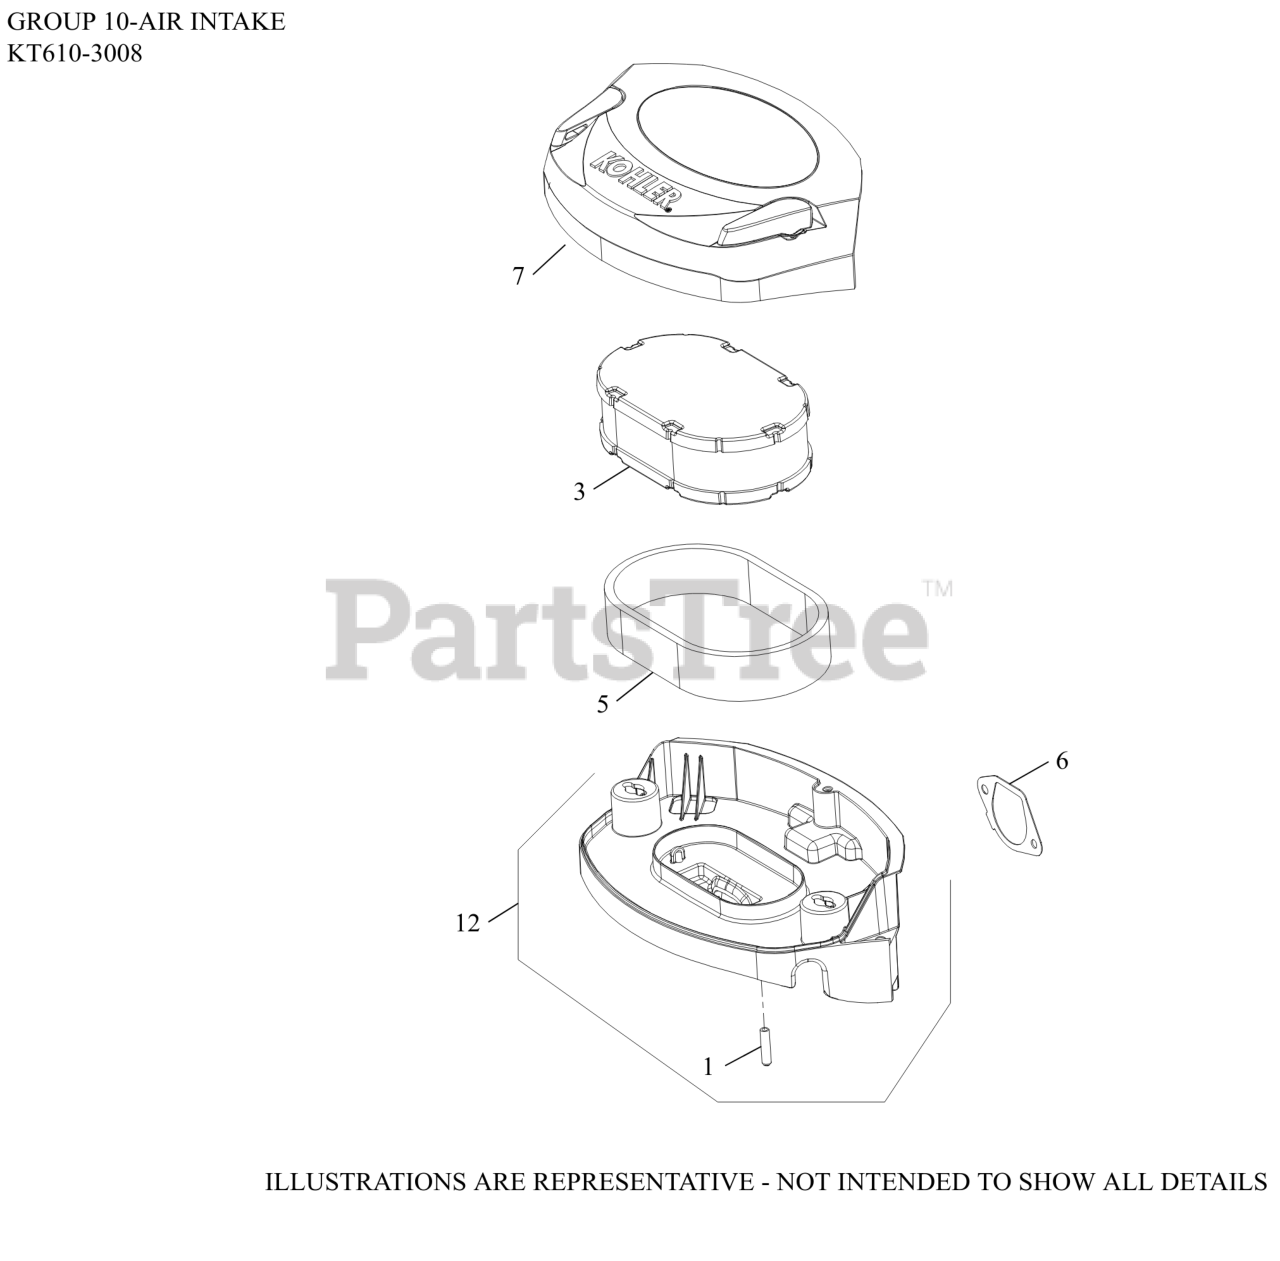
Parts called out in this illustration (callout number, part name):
1	CAP, MASKING
3	ELEMENT, AIR FILTER
5	ELEMENT, PRE-CLEANER
6	GASKET, AIR CLEANER BASE
7	COVER ASSEMBLY, AIR CLEANER
12	BASE ASSY, AIR CLEANER
